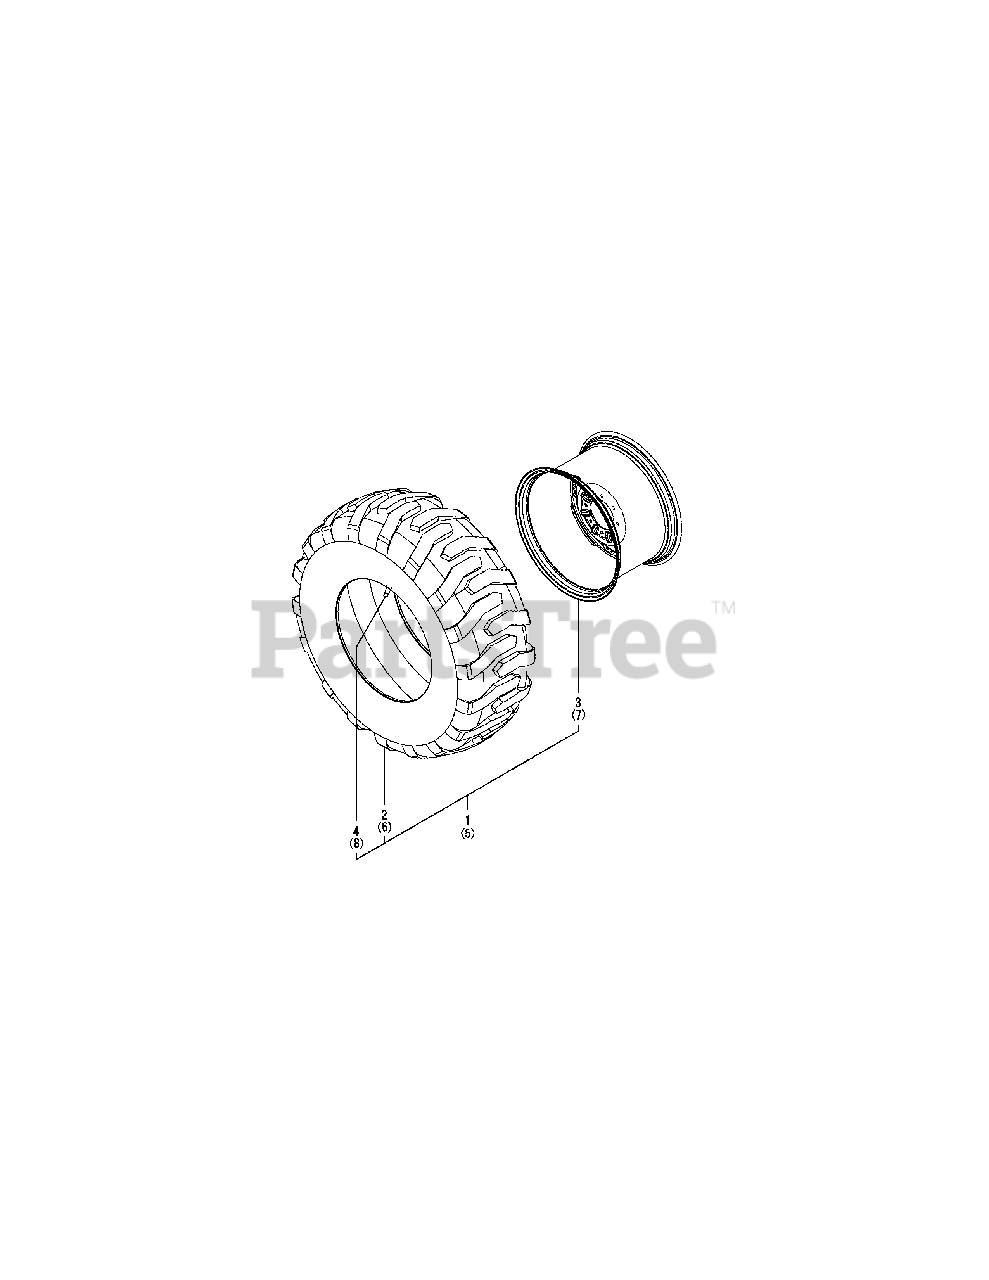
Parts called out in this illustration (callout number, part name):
1	TIRE ASM,L R4 REAR
2	TIRE,R4 17.5L-24-6PR
3	WHEEL,R4 24XW15L
4	VALVE,TIRE R4 REAR
5	TIRE ASM,R R4 REAR
6	TIRE,R4 17.5L-24-6PR
7	WHEEL,R4 24XW15L
8	VALVE,TIRE R4 REAR
